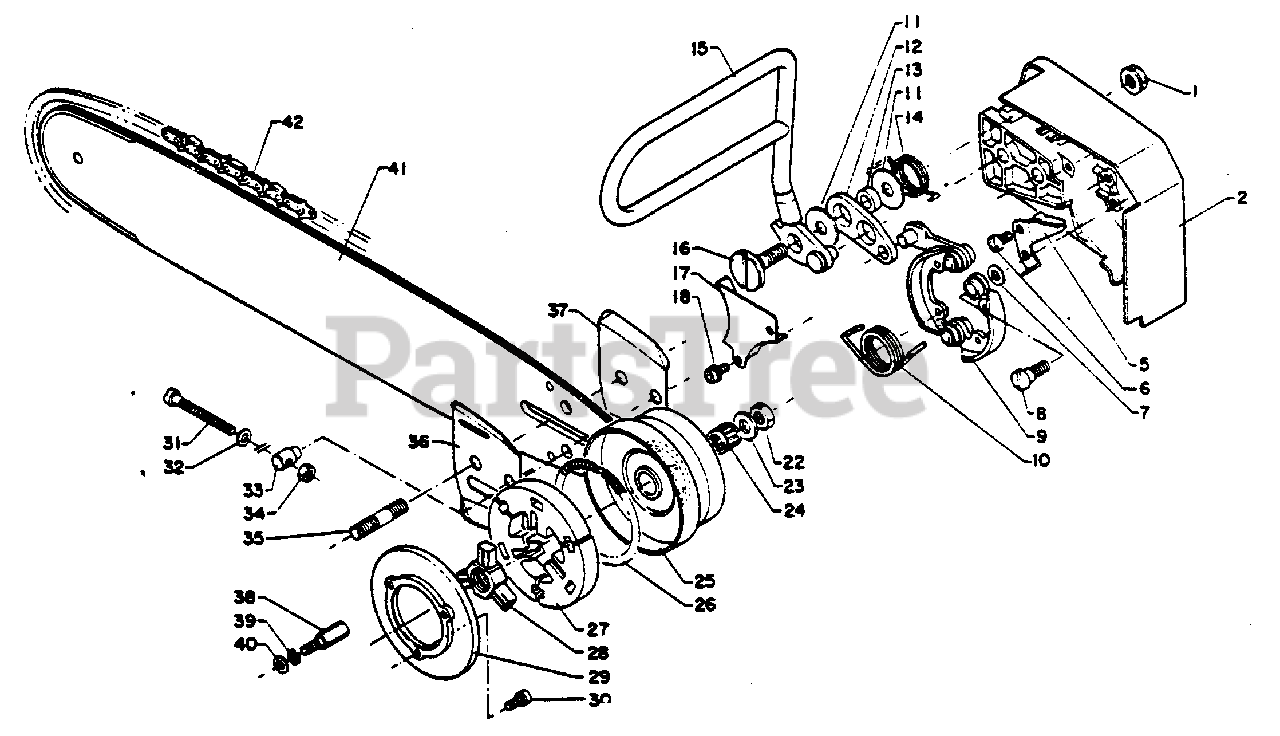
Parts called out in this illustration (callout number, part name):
1	NUT - FLANGE
2	COVER, GUIDE BAR
5	GUIDE, BRAKE SHOE
6	SCREW 5×8
7	WASHER 6.5×11.5×0.8
9	SHOE, BRAKE
10	SPRING
11	SPACER
12	CONNECTOR
13	SPACER, BRAKE HANDLE
14	SPRING, RETURN
15	HANDLE, BRAKE
17	SEAL, DUST
18	SCREW 4×10
22	LOCKNUT
23	WASHER
24	BEARING, NEEDLE
25	DRUM, CLUTCH
26	SPRING, CLUTCH
27	SHOE, CLUTCH
28	HUB, CLUTCH
29	SEAL, DUST
30	SCREW 4×10
31	SCREW, ADJUSTER
32	WASHER
33	TENSIONER, CHAIN
34	LOCKNUT - 5
35	STUD, GUIDE BAR
36	PLATE, GUIDE - INNER
37	PLATE, GUIDE - OUTER
38	CATCHER, CHAIN
39	WASHER, SPRING 5
40	WASHER, FLAT 5.5×10×0.8
41	GUIDE BAR - 16K50
41	GUIDE BAR - 40M50
42	SAWING CHAIN -- 72D-59E
42	SAWING CHAIN -- 72LP-60E
